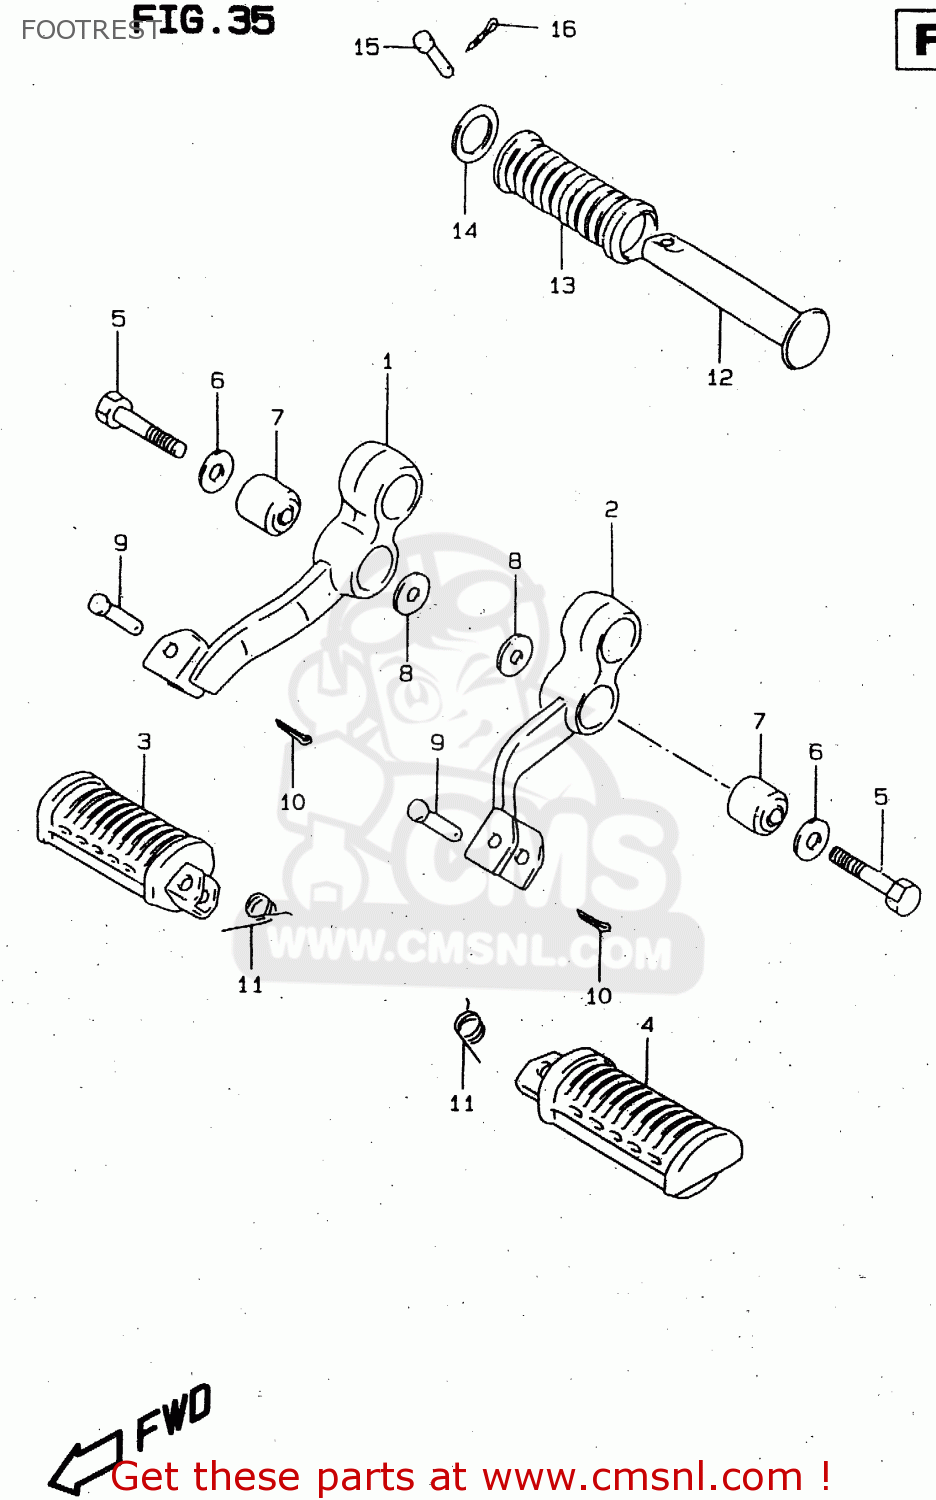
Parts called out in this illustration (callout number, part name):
1	BAR,FRONT FOOTREST,RIGHT
2	BAR,FR FOOTREST,L
3	RUBBER,PILLION FOOTREST,R
4	RUBBER,PILLION FOOTREST,L
5	BOLT(10X35)
6	WASHER
7	BUSH
8	WASHER (10X20X2.3)
9	PIN
10	PIN 20X20
11	SPRING
12	BAR,PILLION FOOTREST
13	RUBBER,PILLION FOOTREST
14	WASHER(19.5X32X2)
15	PIN
16	PIN
